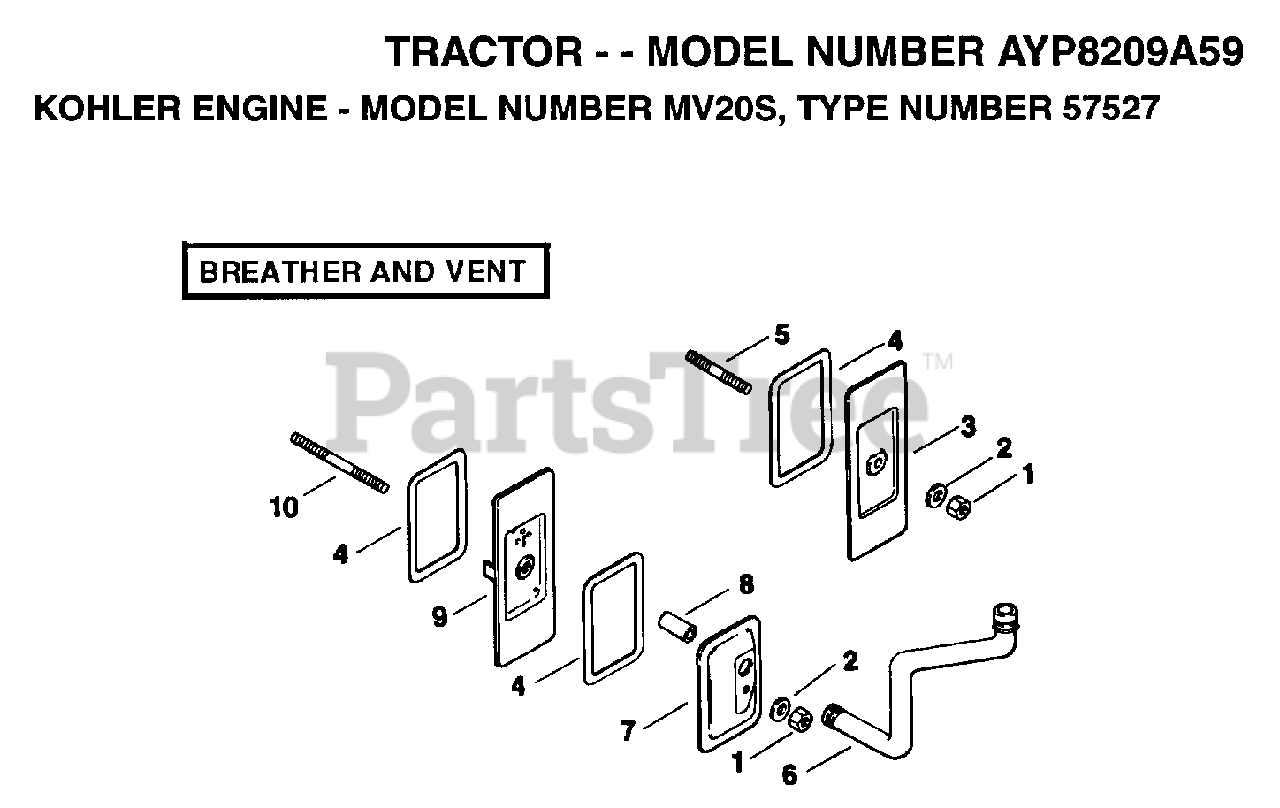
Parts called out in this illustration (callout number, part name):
3	COVER, #2 CYLINDER VALVE
8	SEAL BREATHER
9	BREATHER ASSY
